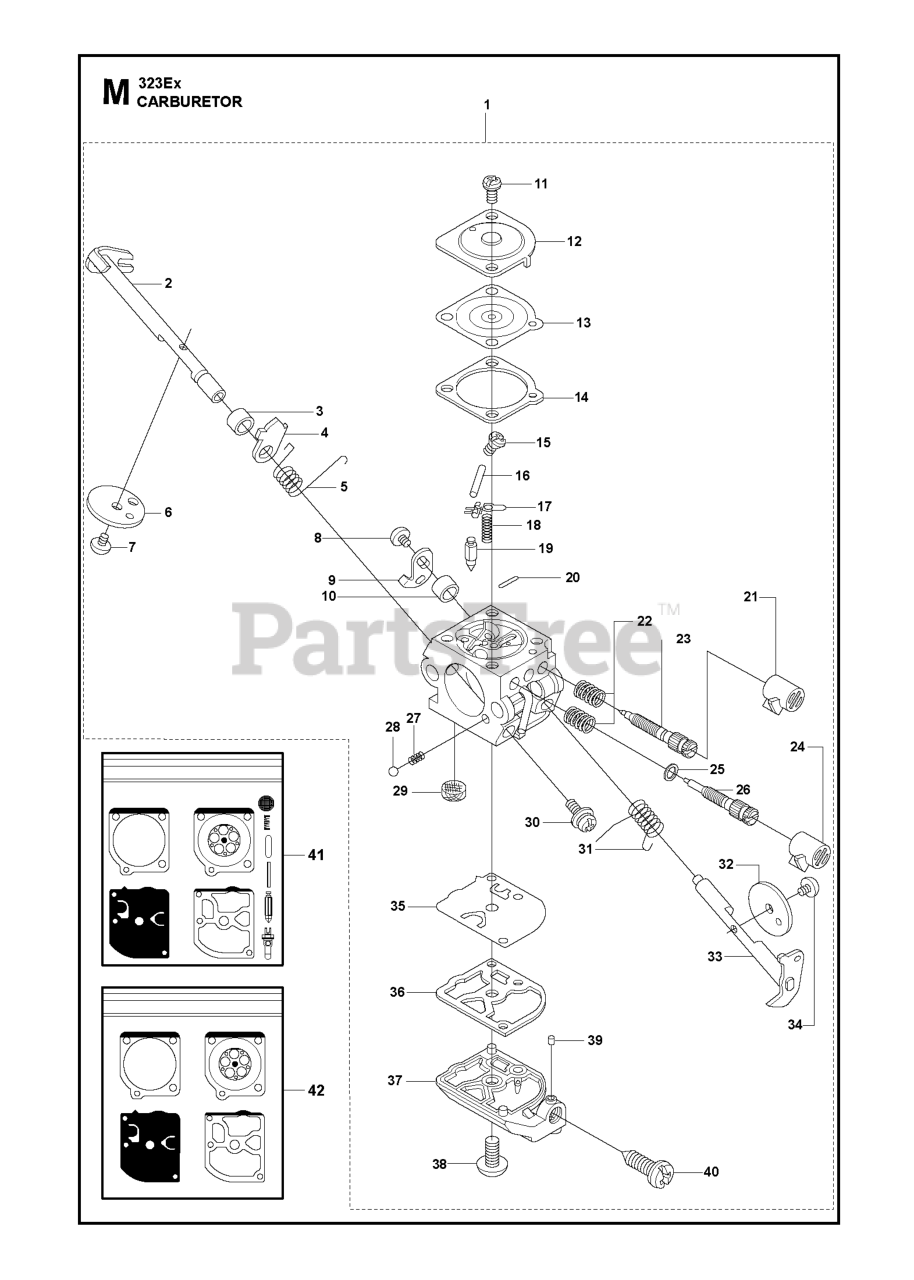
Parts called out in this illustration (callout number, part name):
1	CARBURETOR
2	CHOKE SHAFT
6	DISC
16	PIN RETAINING SCREW
18	SPRING
19	INLET NEEDLE
22	SPRING
23	LOW SPEED NEEDLE
26	NEEDLE HIGH SPEED
31	SPRING THROTTLE
32	THROTTLE FLAP
35	PUMP DIAPHRAGM
41	CARBURETOR KIT (ZAMA RB69)
42	GASKET KIT (ZAMA GND39)
